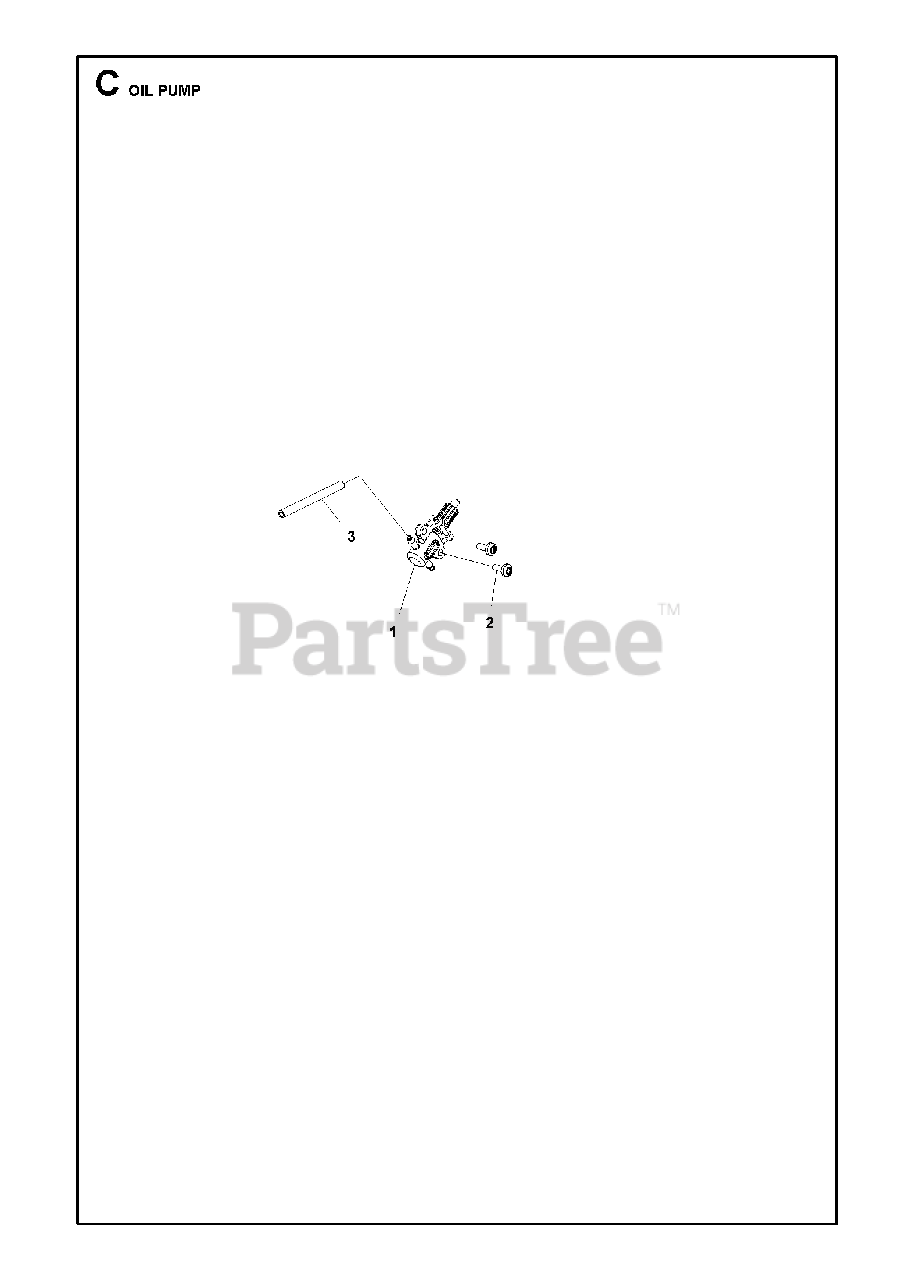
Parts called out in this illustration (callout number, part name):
1	OIL PUMP ASSY 36V CHAINSAW
2	SCREW M4X10 MACHINE SCREW
3	OIL HOSE WHITE AND TRANSPAREN
